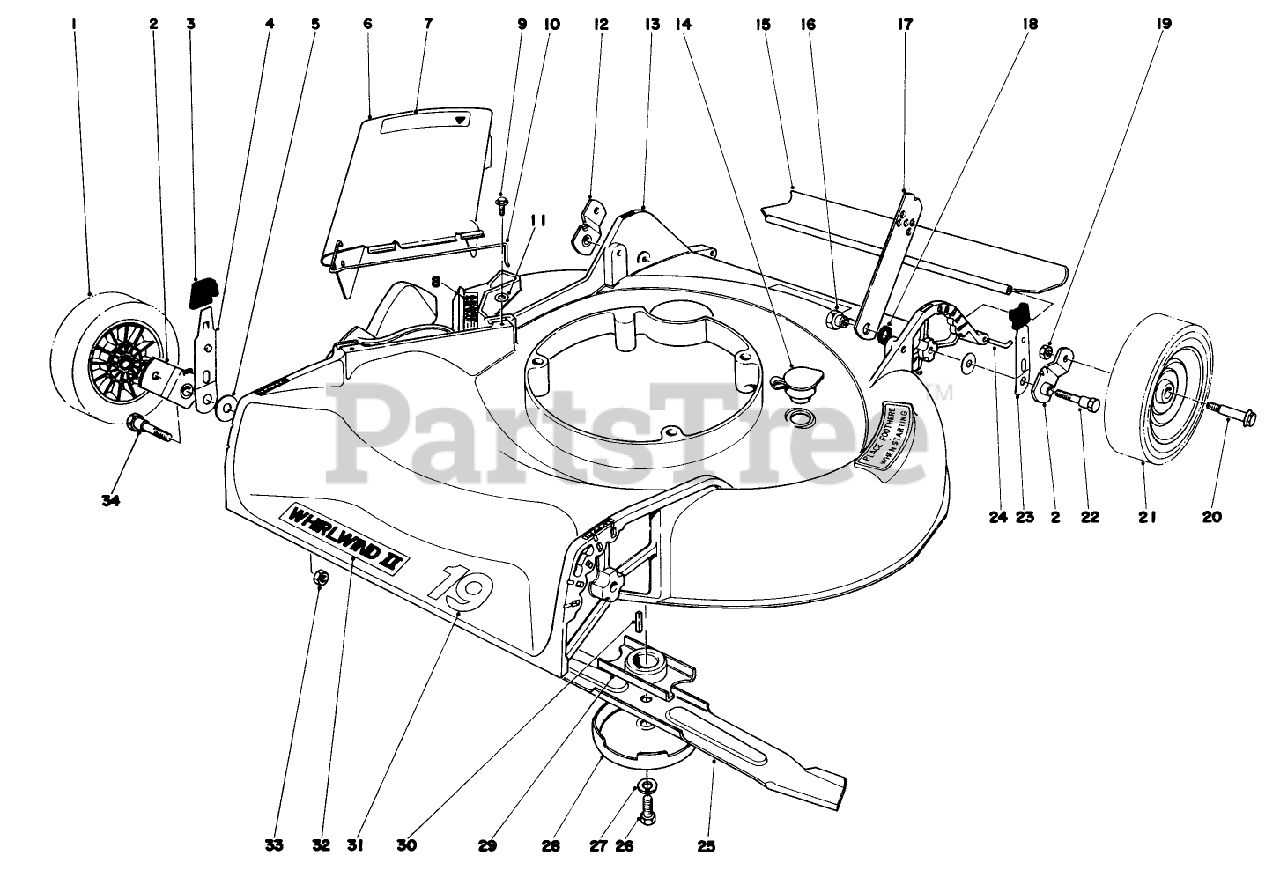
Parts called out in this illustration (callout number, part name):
1	Wheel Tire Assembly
3	KNOB-ARM
4	SPRING ARM ASM
5	Washer
9	SCREW
11	WASHER-FLAT
13	Housing
14	Plug Washout
15	Rear Shield
16	HANDLE PIVOT NUT
18	HANDLE LATCH SPACER
21	Wheel Tire Assembly
22	PIVOT SCREW
27	WASHER-LOCK
28	Anti Scalp Cup
30	KEY-SQUARE
34	PIVOT SCREW
